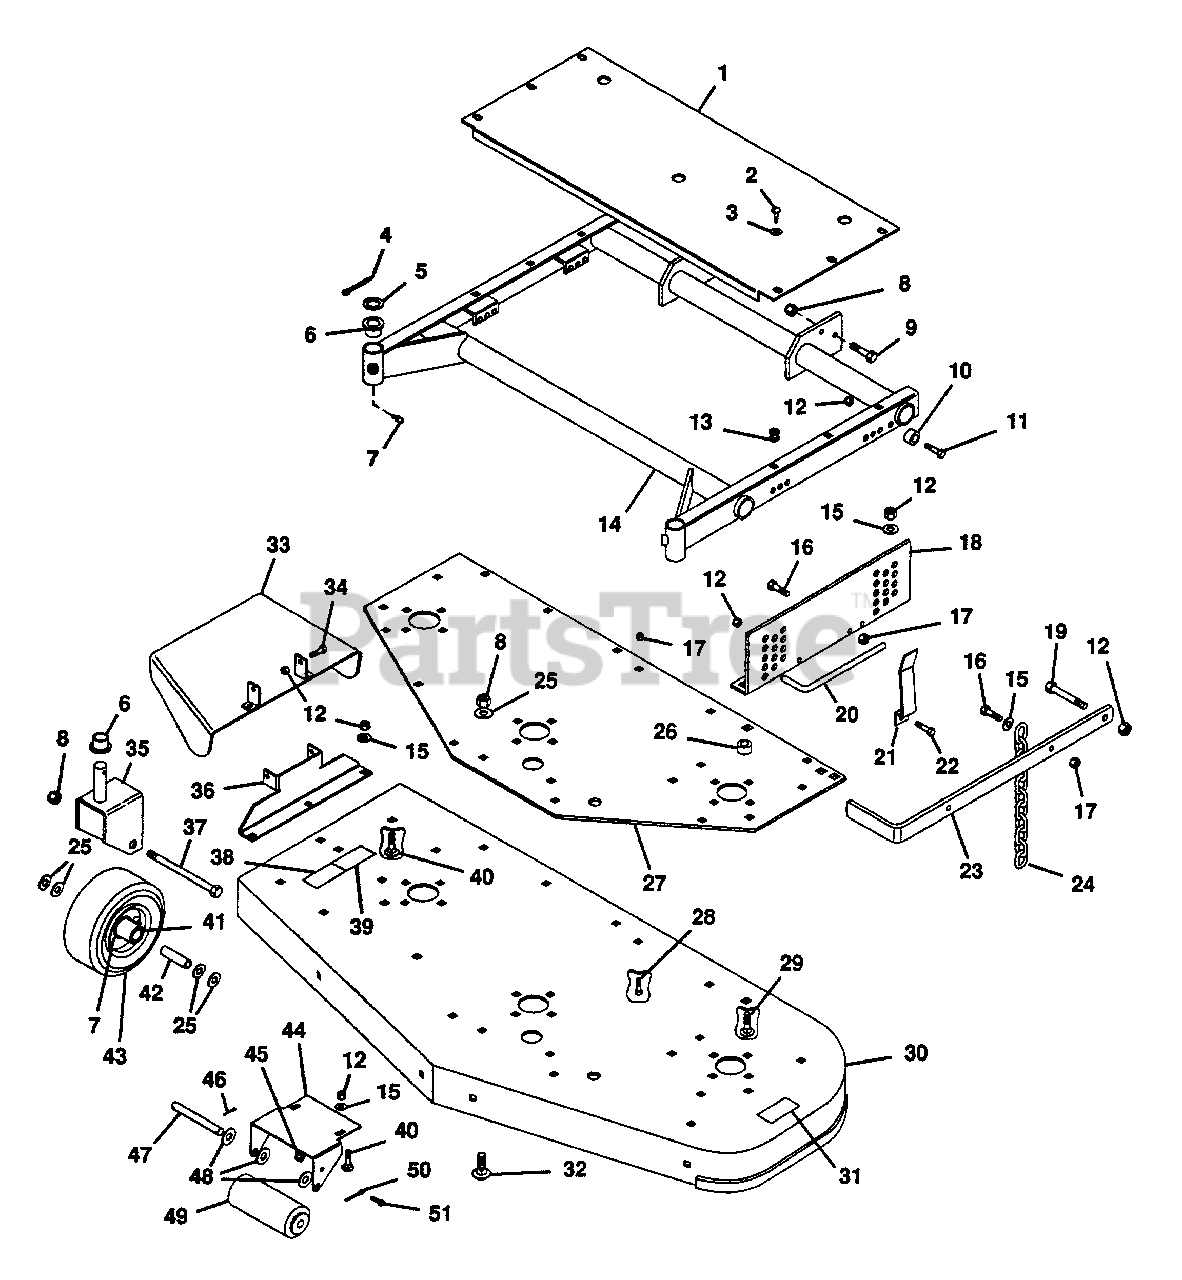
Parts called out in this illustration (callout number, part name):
1	Guard, Belt 60" PM-H Series
2	Screw, 1/4-20x.50 Self Tapping
3	Washer, Flat .281x.625x.065
4	Pin, Cotter .187x1.62
5	Race, Bearing Thrust
6	Bush., Flg. 1.03x1.75x.750 Ny.
7	Fitting, Lube 1/4-28
8	Nut, Lock 1/2-13
9	Bolt, Hex 1/2-13x1.50
10	Bush., St. .391x.621x.676 Stl.
11	Bolt, Hex 3/8-16x1.50
12	Nut, Lock 3/8-16
13	Grommet, Plastic
14	Weldment, Mower Frame
15	Washer, Flat .406x.812x.065
16	Bolt, Hex 5/16-18x1.00
17	Nut, Lock 5/16-18
18	Bracket, Mower Support L.H.
18	Bracket, Mower Support R.H.
19	Bolt, Hex 3/8-16x2.00 Full Thread
20	Pin, Mower Locking
21	Spring, Pin
22	Bolt, Hex 3/8-16x.75
23	Bar, Lift
24	Chain, Height Adjustment
25	Washer, Flat .531x1.25 x.100
26	Bush., St. .406x.750x.188 Stl.
27	Plate, 60" Support
28	Bolt, Hex 5/16-18x.75
29	Bolt, 3/8-16x1.25 Rd Hd Sq Nk
30	Weldment, 60" Mower
31	Decal, Danger Foot
32	Bolt, 1/2-13x1.00 Rd Hd Sq Nk
33	Weldment, Discharge Chute
34	Bolt, Hex 3/8-16x1.00
35	Weldment, Caster Fork
36	Bracket, Discharge
37	Bolt, Hex 1/2-13x5.50
38	Decal, Warning Eye
39	Decal, Danger Hand
40	Bolt, 3/8-16x1.00 Rd Hd Sq Nk
41	Bearing, Gauge Wheel
42	Bush., St. .506x.748x3.34 Stl.
43	Wheel, Gauge
44	Bracket, Roller
45	Nut, Lock 1/4-20
46	Pin, Cotter .25x1.0
47	Shaft, Center Roller
48	Washer, Flat .656x1.312x.095
49	Roller, Gauge
50	Pin, Cotter .25x2.0
51	Bolt, Hex 1/4-20x.75
